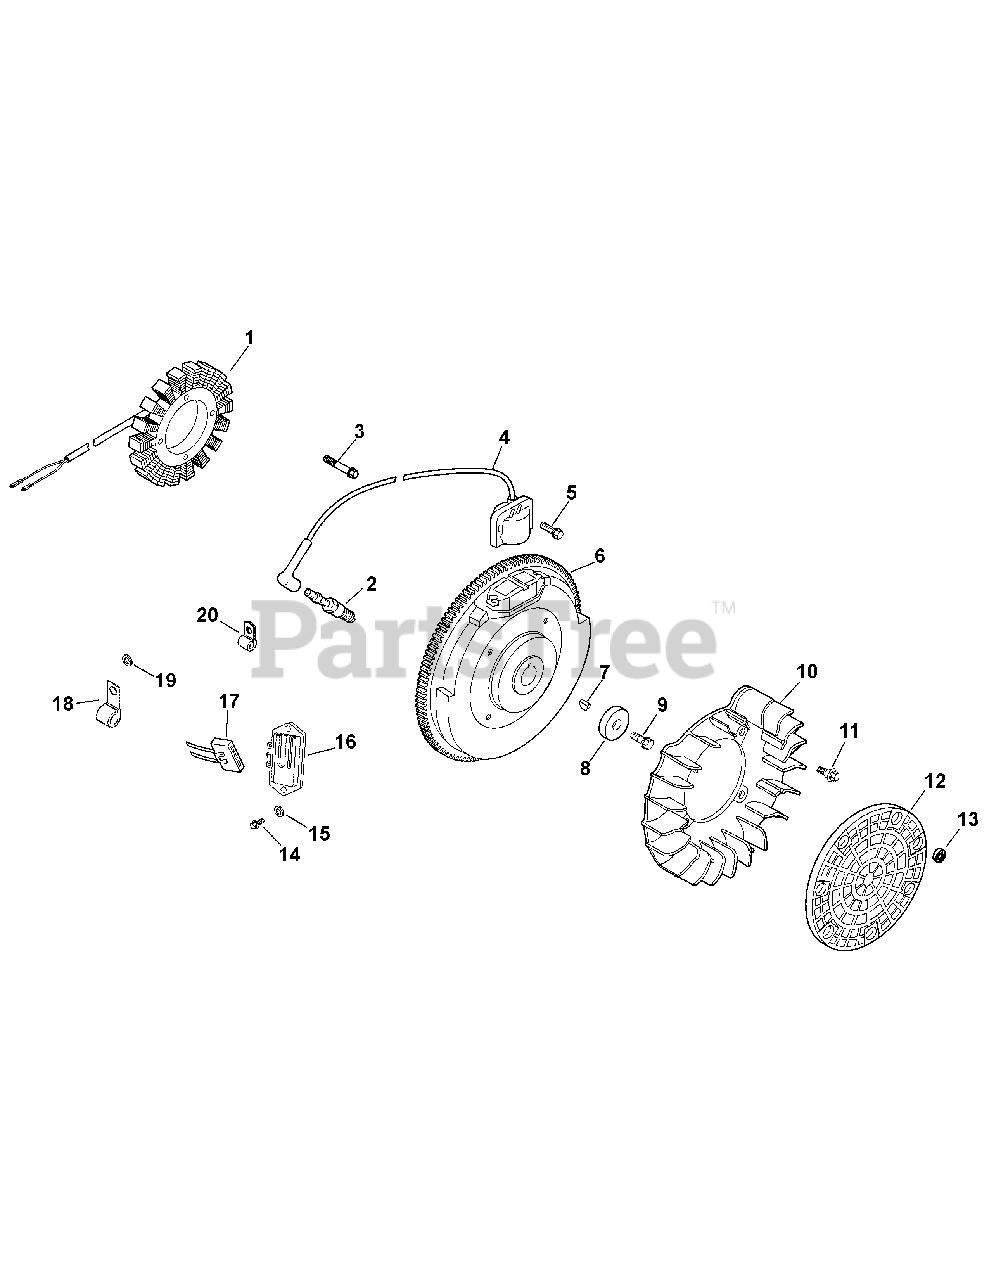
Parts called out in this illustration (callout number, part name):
1	Kit, 15 amp stator
2	Spark Plug (2)
3	Screw, hex. cap M5x0.8x25 (2)
4	Module, ignition (2)
5	Screw, hex. Flange M5x0.8x20 (4)
7	Key, 3/16" x 5/8"
8	Washer, flat 13/32"
9	Screw, hex. Flange M10x1.5x46
11	Bolt, shoulder (4)
12	Screen, grass
13	Retainer, (3)
14	Screw, phillips hd. 11-16x7/8" (2)
15	Washer, plain 3/16" (2)
16	Rectifier-regulator
17	Connector (3 contact)
18	Clip, cable
19	Washer, plain 1/4"
20	Clamp, insulated
